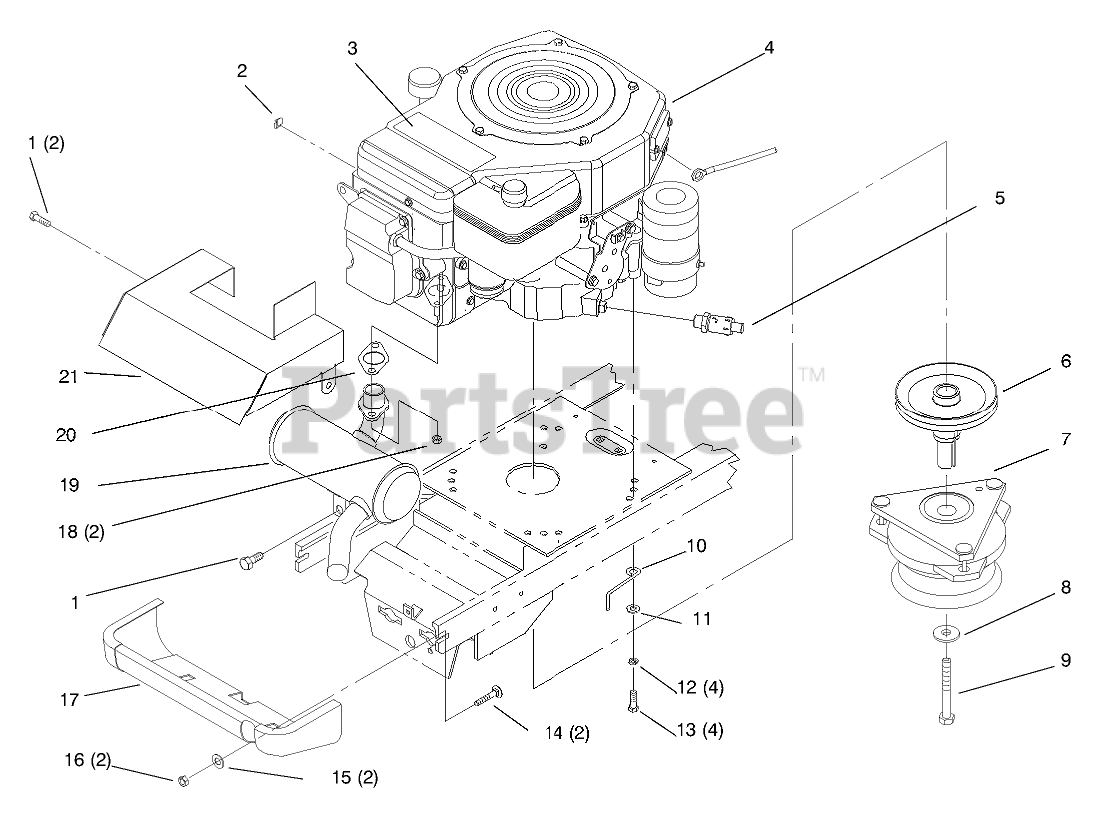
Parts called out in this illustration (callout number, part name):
1	SCREW-HWHTF
2	CLIP-RETAINER, WIRE
3	DECAL - LOGO
4	Engine-Kohler(Only On: 70246)
4	Engine-Kohler(Only On: 70264)
5	VALVE-DRAIN, OIL
6	PULLEY- ENGINE GEAR
7	CLUTCH - PTO
8	WASHER
9	SCREW-HH
10	GUIDE-BELT
11	WASHER-PLAIN
12	WASHER-LOCK
13	SCREW-HH
14	BOLT-CARR
15	WASHER-FLAT
16	NUT-LOCK, NI
17	Shield-Muffler
18	NUT-HF
19	Muffler
20	Gasket-Exhaust
21	SHIELD-MUFFLER
